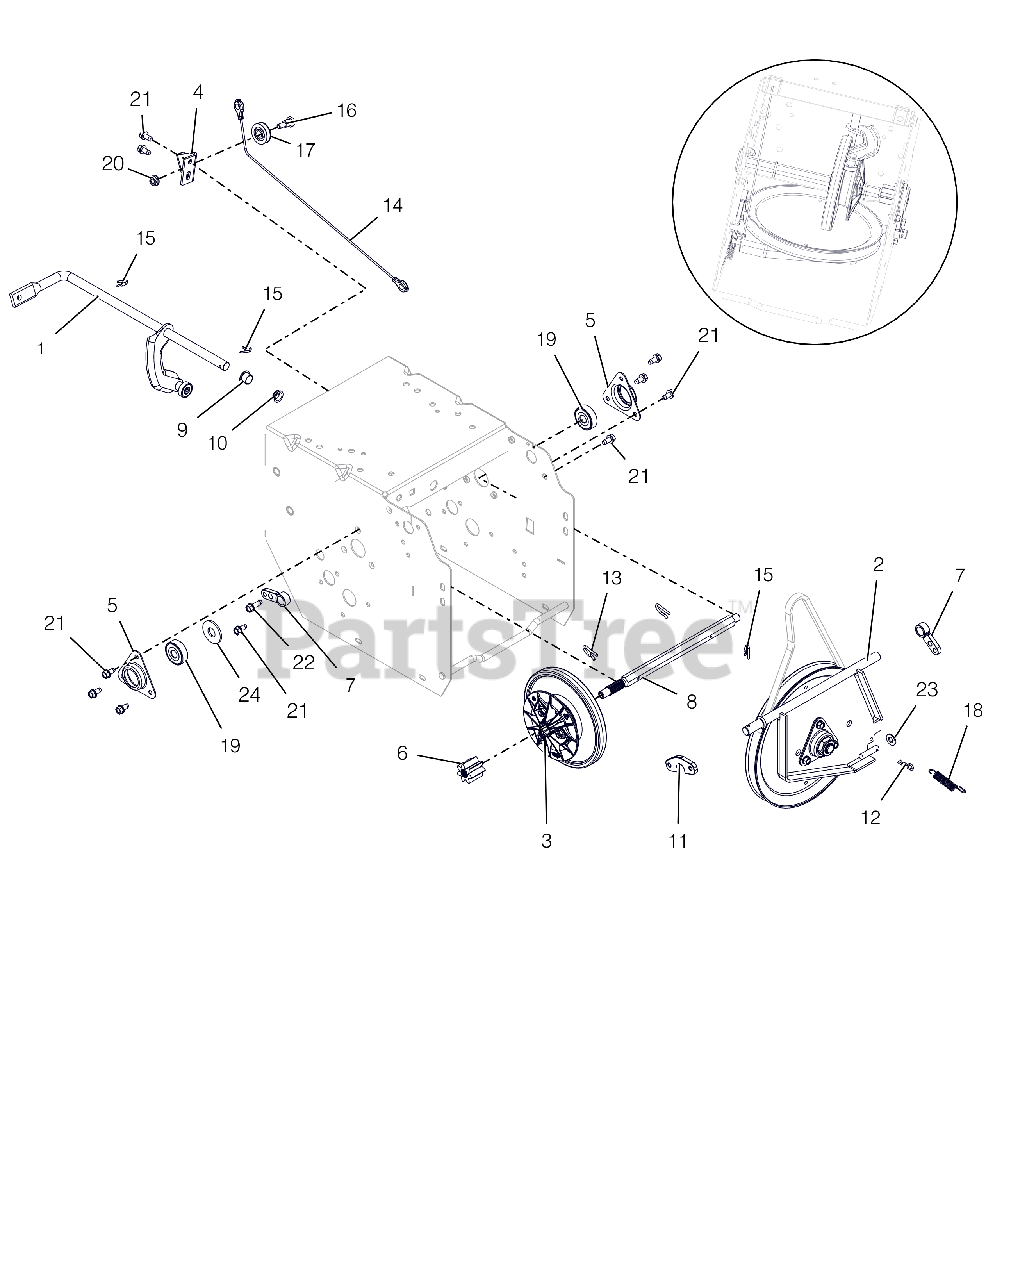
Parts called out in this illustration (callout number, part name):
1	ARM, SHIFT-SMALL DASH (ASSY)
2	PLATE, SWING - ASSEMBLY
3	DISC, FRICTION DRIVE-ASSEMBLY
4	BRACKET, CABLE PULLEY
5	FLANGE, BEARING
6	GEAR, PINION, 7 TOOTH W/SPLINE
7	SUPPORT BUSHING, SWING GATE
8	SHAFT, HEX W/SPLINE
9	BUSHING, POLYLINER-.50 SPLIT
10	BUSHING, POLYLINER-.50 SNAPIN
11	SPACER, SWING GATE
12	PIN-HAIR INT .08X.18X1.18 YWZC
13	PIN, SPRING CLIP
14	CABLE, LOWER TRACTION (CMPCT)
15	CLIP, SPRING
16	BOLT, SHLDR-.375X.375X.25-20
17	PULLEY, CABLE
18	SPRING, EXT. .043X.438X1.64
19	BRG-BALL .437X1.375X.437
20	@NUT-LK-CTR-FLG .25-20 YWZC
21	SCR-TAP .25-20X.50 HWH TR YWZ
22	SCR-TAP-PM .25-20X.75 TR YWZ
23	@WSHR-FL-STL.344X.688X.065YWZC
24	@WSHR-FL-STL.563X1.38X.109YWZC
